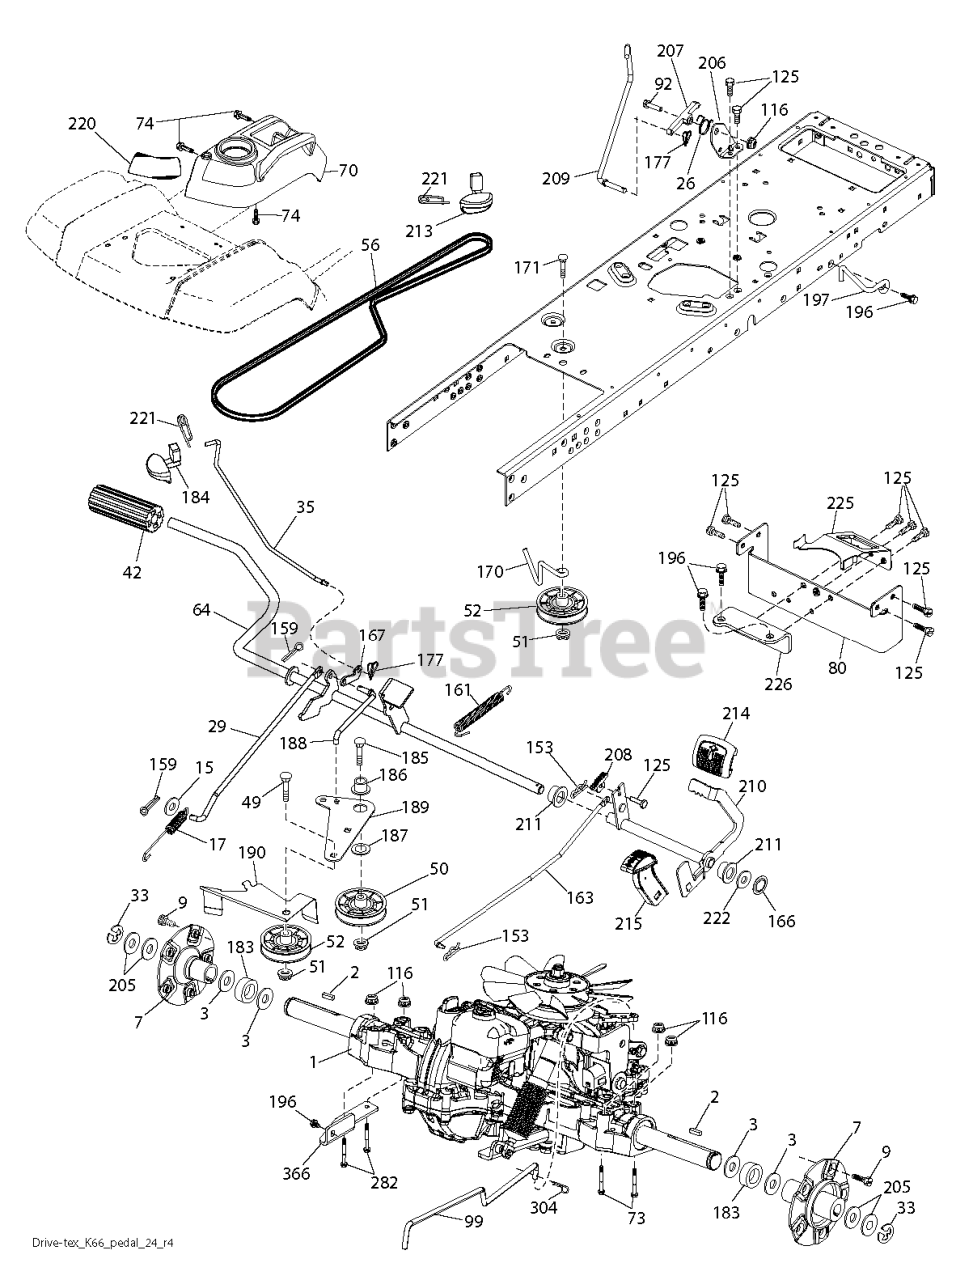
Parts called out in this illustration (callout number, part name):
1	ABSORBER
2	KEY, 1/4 SQ X 1 1/4
7	HUB.PNT.GT.PM.1IN.AXLE.E-DIP
15	WASHER PLAIN WASHER 3/8 X 0.08
17	SPRING.BRAKE.K46
26	SPRING.RETURN.CRUISE
29	ROD.BRAKE.K66
33	E RING HYT
35	ROD ROD.PARKINGBRAKE.GT.HUSQ/P
35	ROD .BRAKE. PARKING. GT. HUSQ.
42	PEDAL COVER
50	IDLER.FLAT.910.OFFSET
51	NUT LOCK FLG 3/8-16 UNC
52	IDLER.V-GROOVE.910.OFFSET
56	BELT.DRIVE.T2.K66
64	SHAFT.ASM.PEDAL.BRK.CNTR
70	CONSOLE.ASM.RH.GT.FC.HUSQ
80	STRAP.PNT.TORQUE.K66.EDIP
99	ROD.BYPASS.K66
125	SCREW
153	RETAINER M
161	SPRING, RETURN LT
163	ROD.PEDAL.CONTROL
166	NUT.PUSH.625
167	LATCH.BRAKE.SPRING
170	KEEPER.V-IDLER.CENTER.
177	GSPW Retainers
177	PIN COTTER;LOCKING;BOWTIE;1IN
183	SPACER.SPLIT;1.00.ID 1.75"
183	SPACER.SPLIT.1.000IDX1.75
184	HANDLE.PARKING.BRAKE.H (BLK)
186	SPACER.RETAINER
188	LINK.CLUTCH.GROUND DRIVE.LONG
189	BELLCRANK.GROUND.DRIVE.TEX.
190	KEEPER.BELLCRANK.DRIVE
196	SCREW 3/8-16X1
206	BRACKET.MOUNT.CRUISE.LATCH
209	ROD ROD.CRUISECONTROL.GT.HUSQ/
209	ROD.CONTROL.CRUISE.GT.
210	ROCKER.ASM.PEDAL.CONTR
211	BEARING.NYLON
213	KNOB.CONTROL.CRUSIE.HU
214	PEDAL.FORWARD.PAD.TEX
215	PEDAL.COVER.REVERSE.CRD.X428BK
220	REFLECTOR.RH.TEX GT
221	RETAINER.SPRING.CLIP.H
222	WASHER 21/32 X 1-1/4 X 10 GA.
225	KEEPER.BELT.TRANSAXLE.K66
226	BRACKET.MOUNT.TORQUE.K66.TG
282	BOLT HEX FLGHD 5/16-18X3 GR. 5
304	HAIRPIN.SOFT.ZINC.059X1.125
366	BRACKET REINFORCEMENT BLACK. E
366	BRACKETS
366	BRACKET.REINFORCEMENT
